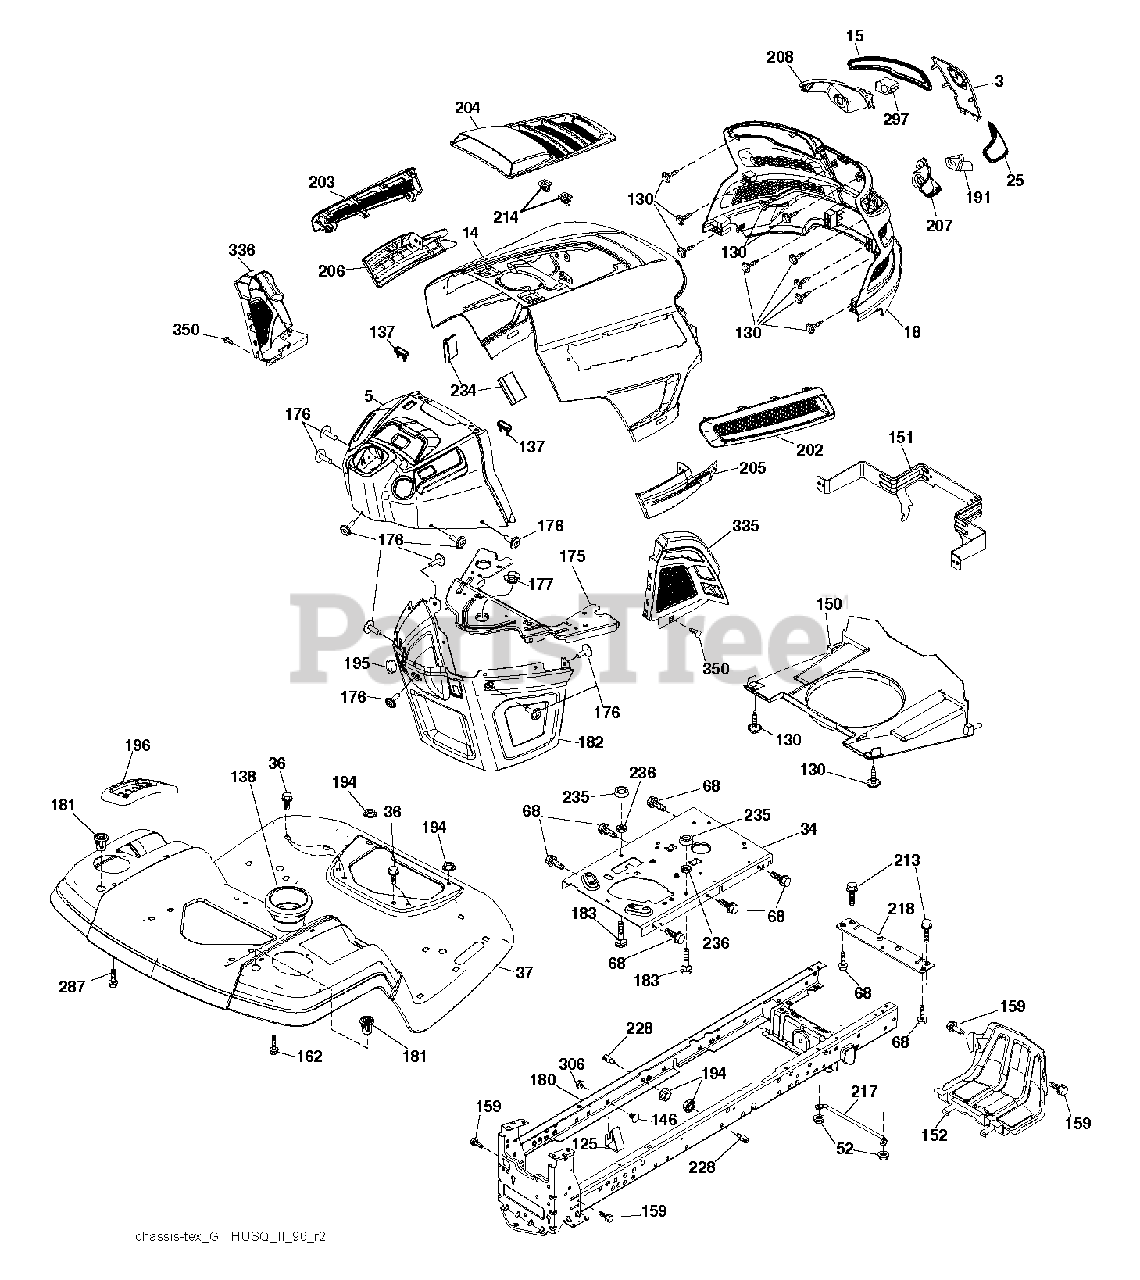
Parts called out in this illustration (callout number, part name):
3	APPLIQUE.SUBASM.GT.HUSQ.II
5	DASH.W/O.BUMPERS.RS.
14	HOOD.ASM.HUSQVARNA.GT.TEX.ORAN
15	LENS.HEADLIGHT.LH.GTII.2011
18	GRILLE.SUBSTRATE.2011.
25	LENS.HEADLIGHT.RH.GTII.2011
34	PLATE.ENGINE.WELDED.CHASSIS
36	SCREW 5/16"
37	FENDER.TLT.PDL.CNTRL.W/CPH.ORG
52	LOCKNUT
68	SCREW LT
125	CLIP.FUEL.LINE
130	SCREW.#10 X 0.750.BOS
137	BUMPER DASH
138	HOLDER.CUP.LT.GREY
146	BOLT.RDHD.SHT.SQNK.3/8-16X5/8
150	AIR.DUCT.GTV.BLACK
151	BRACKET.PIVOT.HOOD.GT.HUSQ.II
152	SHIELD.BROWNING.PNT.GT.V2
159	SCREW, 3/8-16X3/4
162	SCREW.HI-LO.CONSOLE
175	PLATE.CROSSMEMBER.HUSQ
176	SCREW.#10-24X5/8.RN.QU
177	BUSHING STEERING
180	CHASSIS
181	BUSHING.MNT.FEND.CRGO.TEX.49
182	DASH.LOWER.COMMON.12V.ADAPTOR
183	BOLT.5/16-18X1-1/4 FULL THD
191	INSERT.REFLECTIVE.RH.HUSQ.GTII
194	NUT LOCK HEX FLANGE 5/16-18
195	PLUG.HOLE.DASH.LOWER.12V.BLK
196	DECKLFT.CONSOL FULL ASSM GREY
202	VENT.SIDE.RH.GT.HUSQ.II.
203	VENT.SIDE.LH.GT.HUSQ.II.498
204	VENT.TOP.HUSQ.GT2
205	SIDE.TRIM.RH.GT.HUSQ.II
206	SIDE.TRIM.LH.GT.HUSQ.II.GRAY
207	BEZEL LIGHT.RH.GT.II.MYLAR
208	BEZEL LIGHT.LH.GT.II.MYLAR
213	BOLT
214	CLIP.RETAINER.TINNER.
217	ROD.PIVOT.HOOD
218	X-PIECE.HOOD.STOP.NON/
228	STUD.FASTNER.W/ANTI-ROTATE
234	BUMPER.HOOD.TEX.HUSQVARNA
235	SPACER FENDER
236	NUT.CENTERLOCK.5/16-
287	SCREW 1/4X20
297	INSERT.REFLECTIVE.LH.HUSQ.GTII
306	NUT LOCK FLG 3/8-16 UNC
335	COVER.LOWER.DASH.RH.BLACK
336	COVER-LH.LOWER.DASH.GT2.BLACK
350	CLIP.X-MAS.TREE
